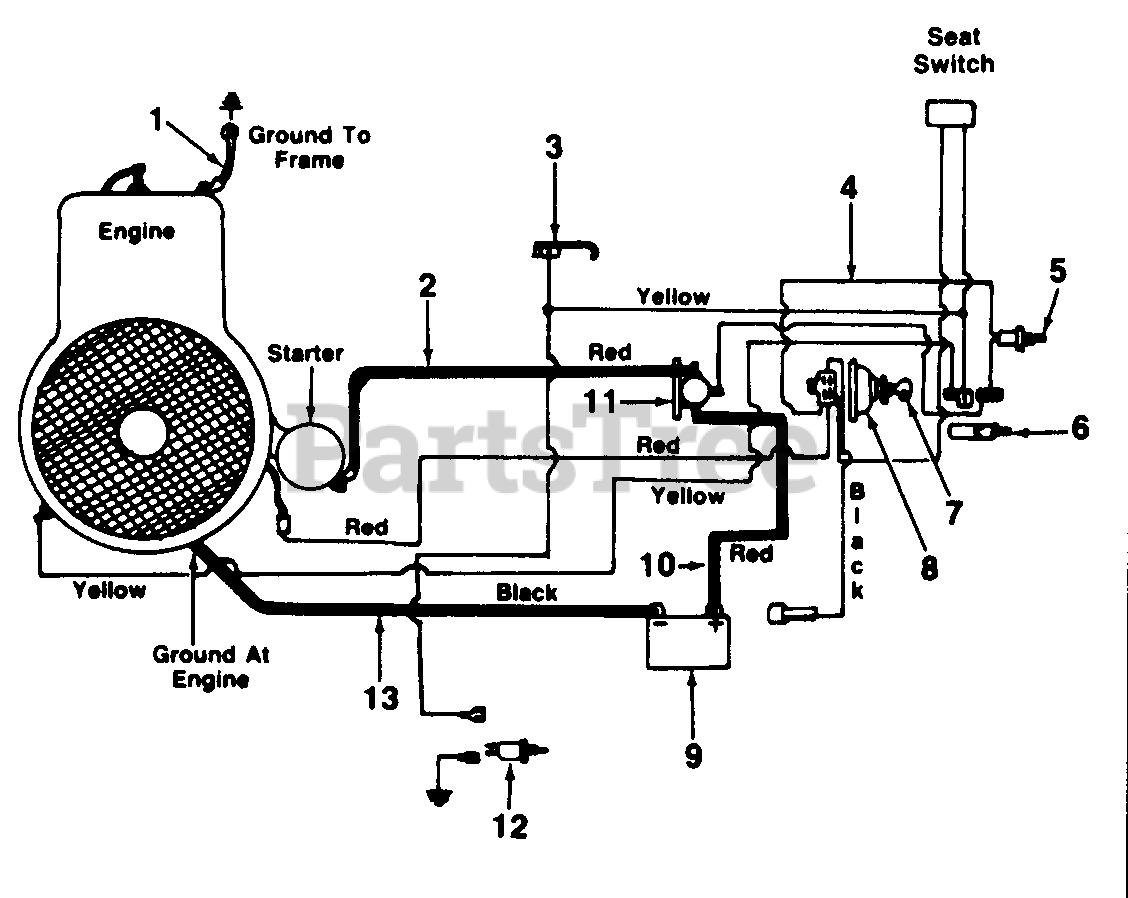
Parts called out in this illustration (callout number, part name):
1	Elec. Wire 8 Ga. x 9 on Lg.
3	Spring Switch-Reverse
4	Wire Harness
5	Safety Switch-Black N.O.
6	Safety Switch
7	Ignition Key
8	Ignition Switch
9	Battery 12V
10	Elec. Wire Red w/Boot
11	Solenoid
12	Safety Switch Red N.C.
13	Elec. Wire 8 Ga. x 9.0" Lg.
